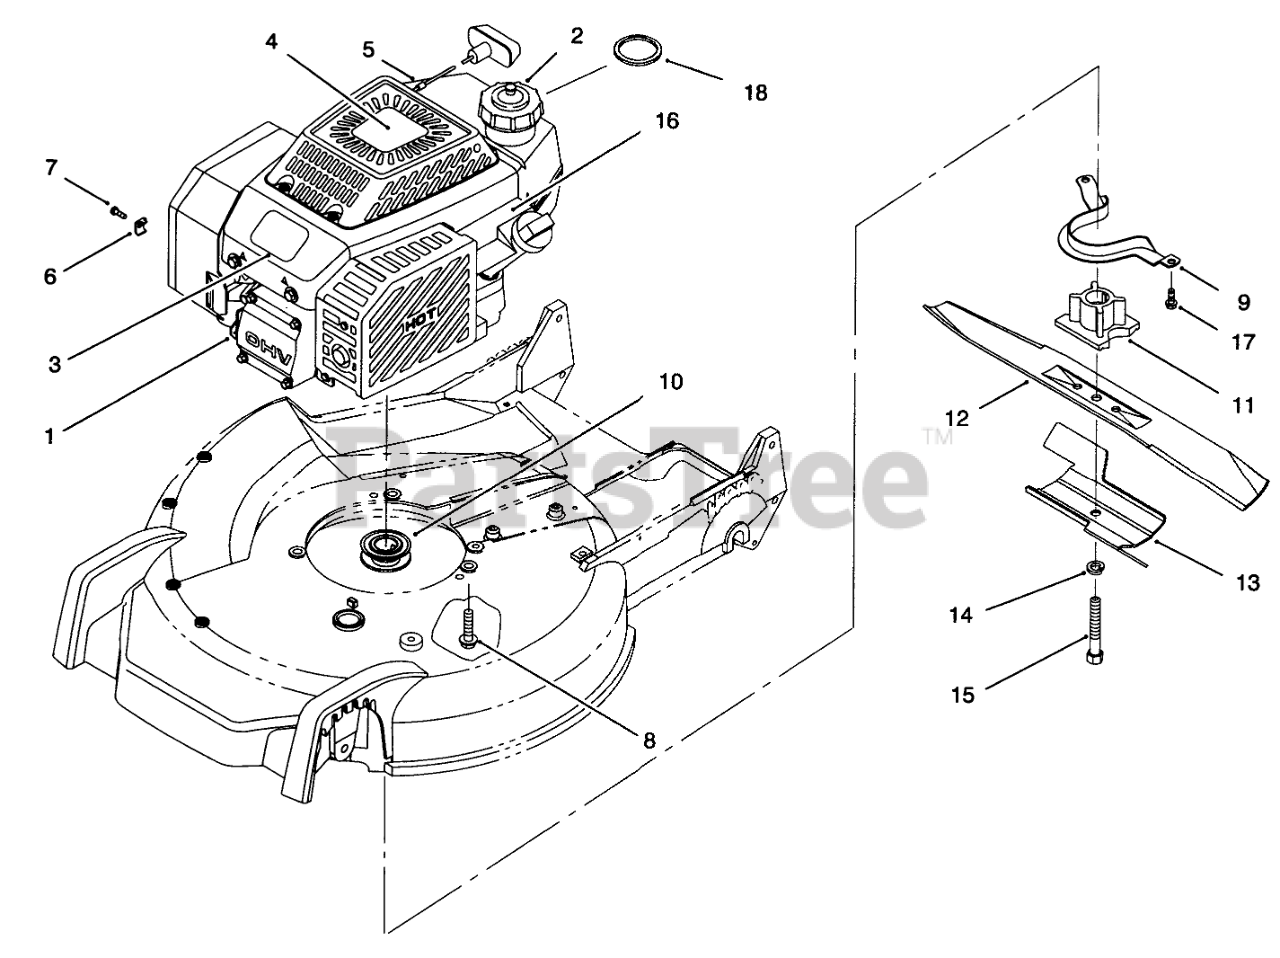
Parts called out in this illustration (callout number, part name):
1	Engine
2	Cap-Fuel Asm. (Incl. Ref. #18)
3	PLATE-LOGO
4	DECAL - ENGINE
5	STOP-ROPE
6	CLAMP-CASING
7	CLAMP SCREW F/W ENGINE
8	SCREW-HWH
9	Guide-Belt
10	PULLEY-DRIVE, ZONE START
11	RETAINER - BLADE
12	Blade
13	Stiffener-Blade
14	WASHER-LOCK
15	SCREW-BLADE
16	COVER - BRAKE F/W
17	SCREW-HWHTF
18	GASKET (FOR 94-5575)
